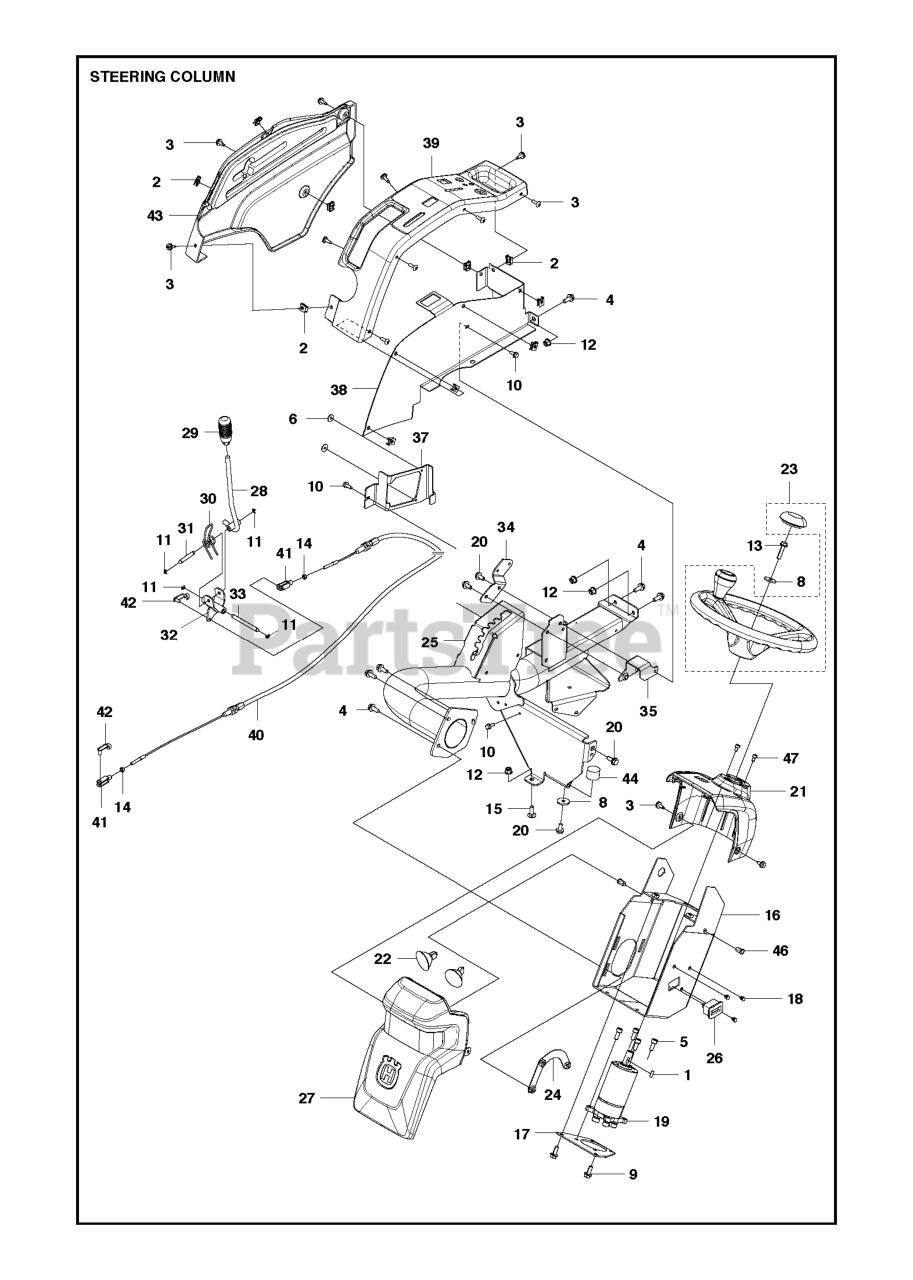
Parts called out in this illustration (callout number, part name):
9	SCREW MC6S 6X10
12	NUT FLANGE
13	SCREW EHHFM
22	LIGHT
29	GEAR STICK KNOB
30	HAIR PIN SPRING
44	ANTIVIBRATION ELEMENT
47	BOLT
